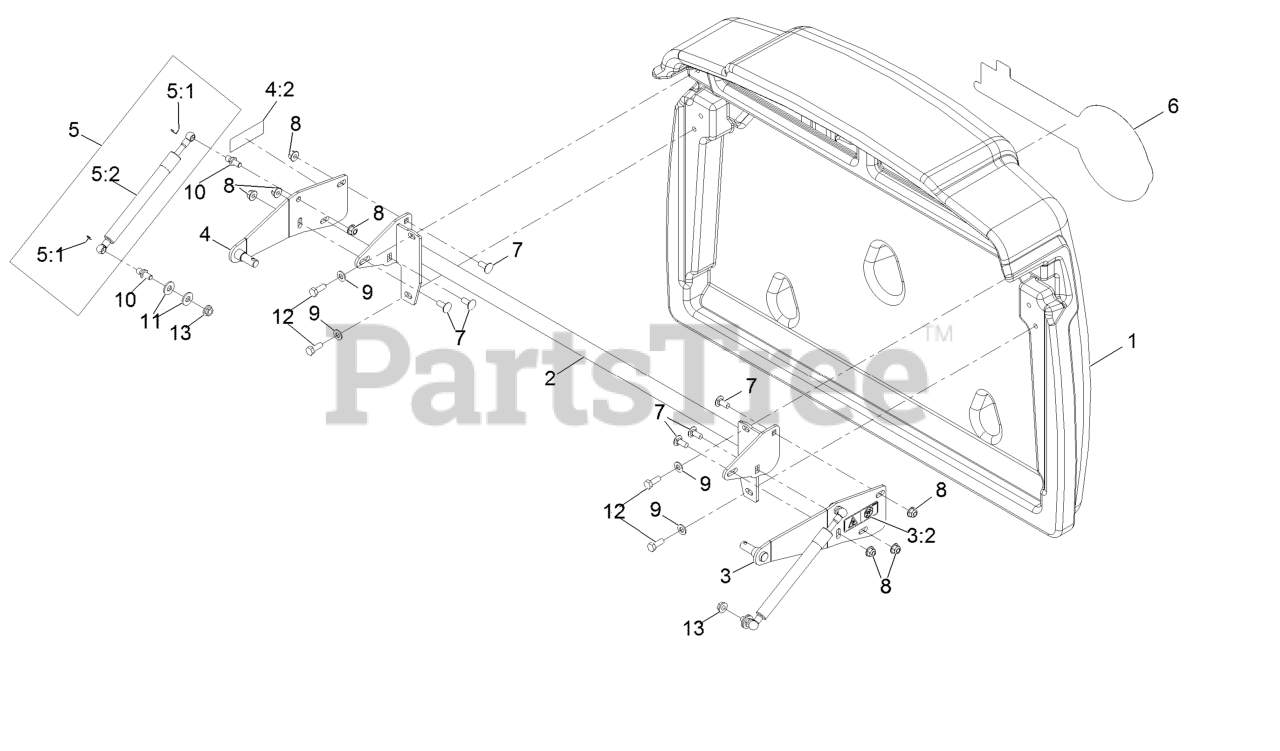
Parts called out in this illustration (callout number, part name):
1	Door, 9.5 Bushel Hopper
2	Support-Door
3	LH Door Pivot ASM
3:2	Decal-Warning, Pinch Point
4	RH Door Pivot ASM
4:2	Decal-Warning, Pinch Point
5	Damper Kit
5:1	Clip-Retainer
5:2	Shock-Gas Tension
6	Decal-Exmark Logo
7	Screw-CARR
8	Nut-HF, NI
9	Washer-Plain
10	Stud-Ball
11	Washer-Flat
12	Screw-HH
